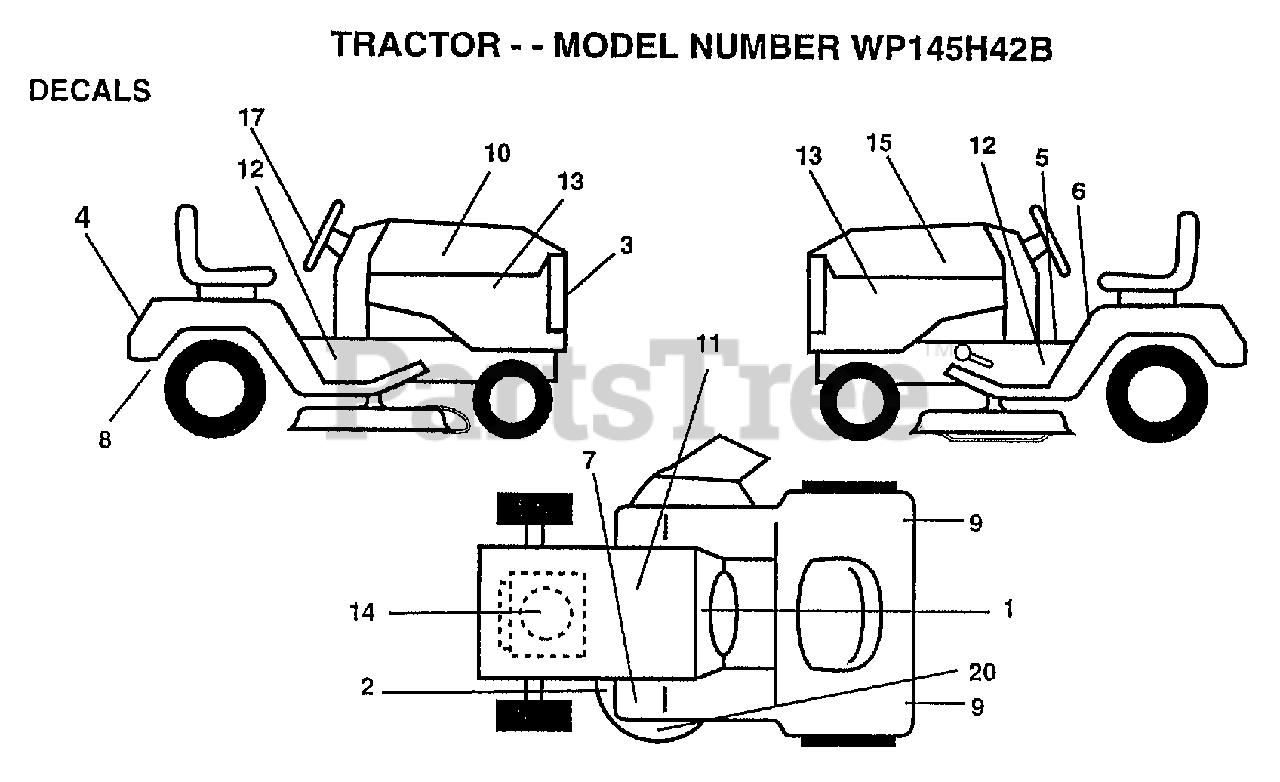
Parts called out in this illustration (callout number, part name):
1	"DECAL-INST,OPER"
2	DECAL
3	DECAL GRILLE
4	DECAL, FENDER LOGO
5	DECAL BRAK PARK
6	"DECAL DANGER,FEND"
8	DECAL DRAWBAR LH
9	REFLECTOR-TAIL YT
10	DECAL.HOOD.RH
11	DECAL.BATRY.3-3908
12	DECAL CHAS 42 HYD
13	DECAL.WP145H42A
14	DECAL, ENGINE
15	DECAL.HOOD.LH
17	DECAL, INSERT
20	"DECAL,ENVIRO DECK"
